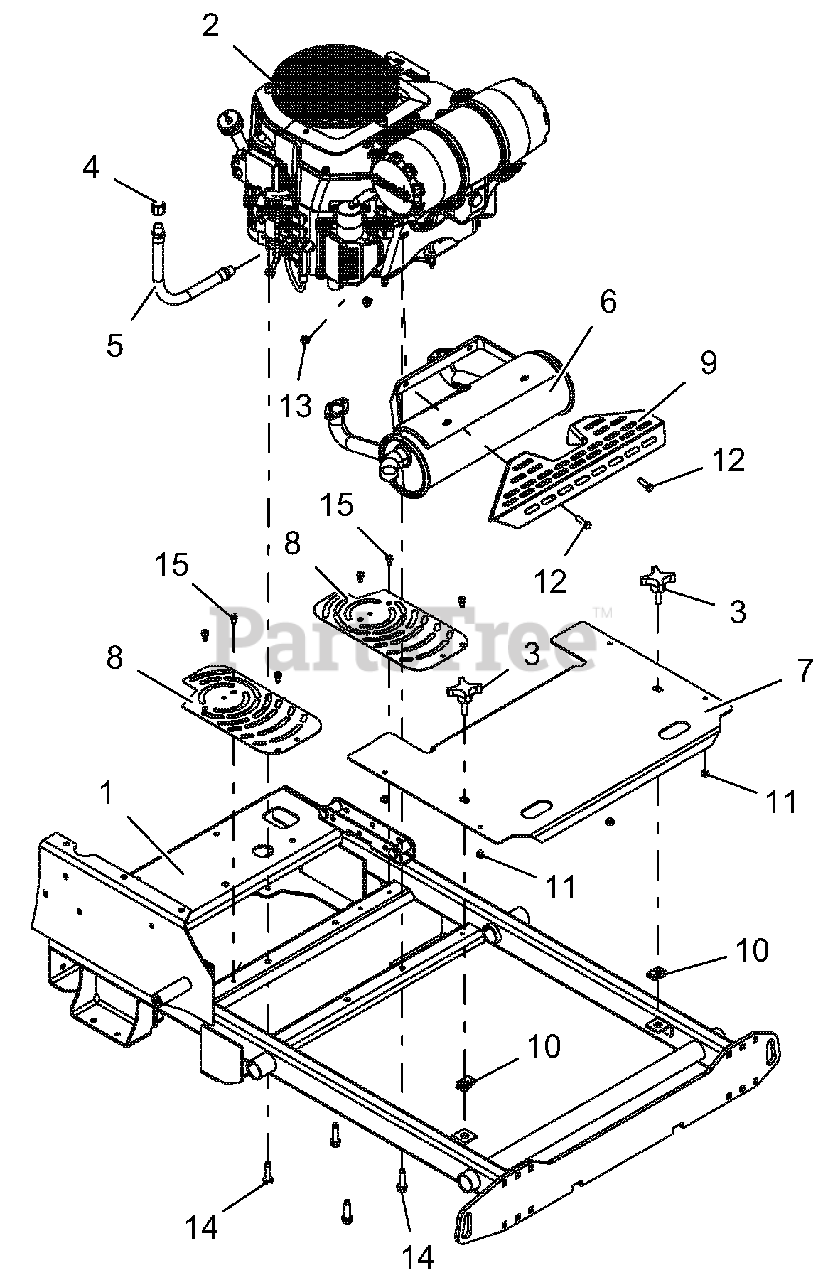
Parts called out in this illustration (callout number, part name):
1	WLDMT, FRAME PROSTANCE
2	ENGINE, KOHLER PVC740 EFI LP
3	KNOB, 3/8 X 1.25 - 4 PRONG
4	PIPE, CAP 3/8 NPT FEMALE
5	HOSE, HYD .38-11-OK M6N0-M6N0
6	MFLR, KOHLER
7	SHIELD, FRONT PRO-STANCE-RED
8	GUARD, FAN
9	GUARD, HEAT SHIELD (BLACK)
10	NUT, RTNR .375-16X.37
11	BUMPER GROMMET .125 X .25 REV
12	BLT-HEX .31-18X1.00 GR5 YWZC
13	NUT-LK-NYL-FLG .31-18 YWZC
14	SCR-TAP .38-16X1.50 HWH TR YZ
15	SCR-TAP .25-20X.50 HWH TR YWZ
